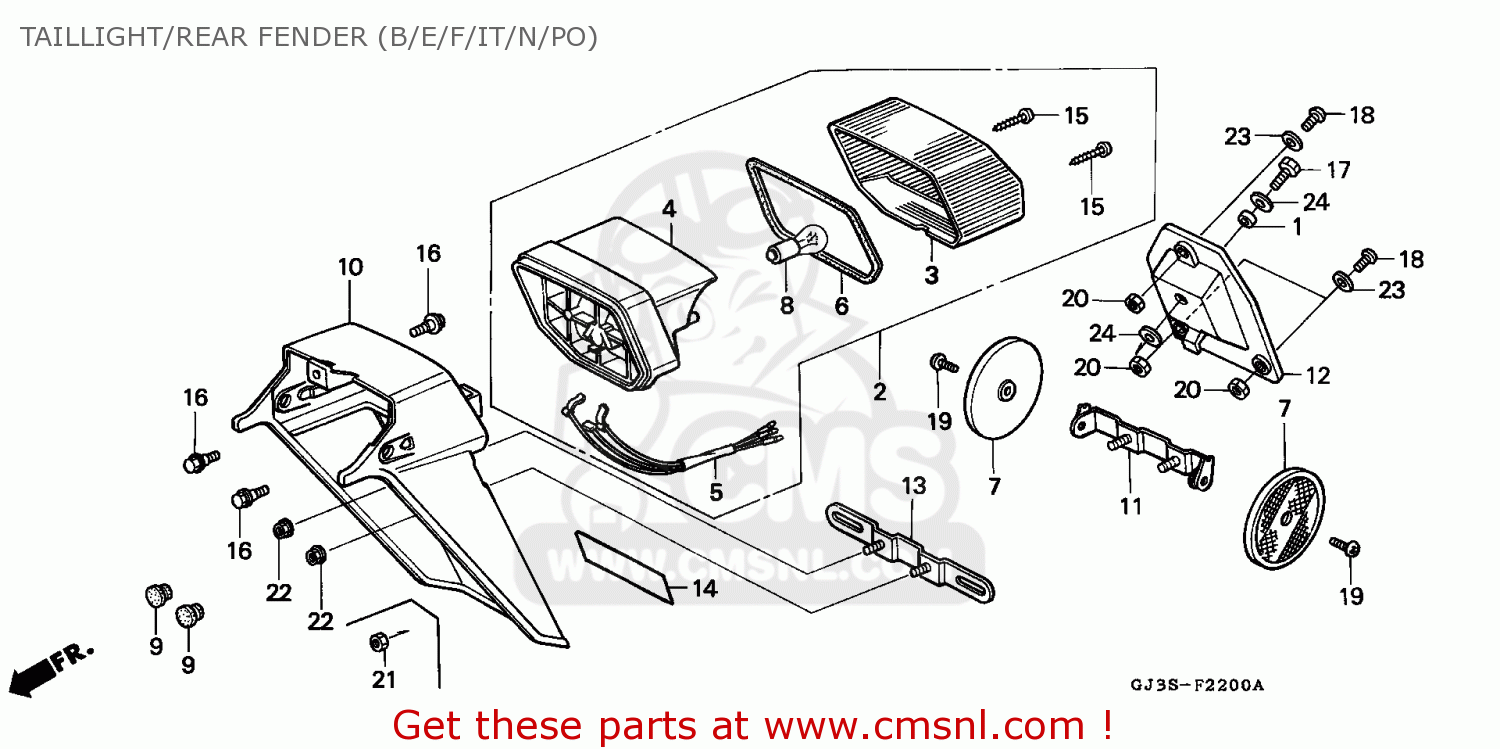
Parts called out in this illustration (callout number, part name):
2	UNIT TAILLIGHT
3	LENS TAIL STOP
4	BASE TAILLIGHT
5	CORD COMP.,TAILLI
6	PACKING TAILLIGHT
8	BULB (12V21W-5W)
10	FENDER A,RR.
13	PLATE,NUMBER SETT
15	SCREW TAPPING 3.5X35
16	BOLT,SPECIAL,5MM
22	NUT,FLANGE,5MM
